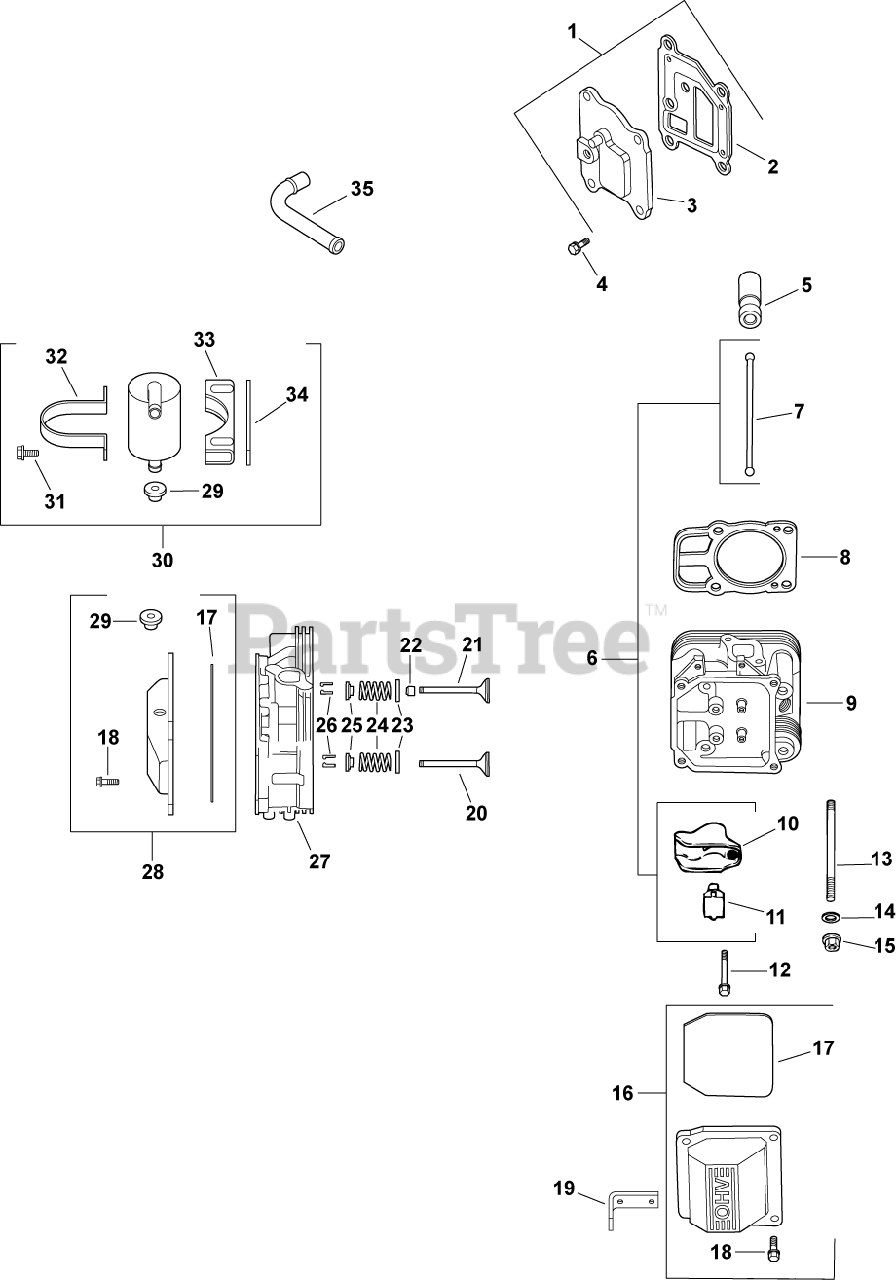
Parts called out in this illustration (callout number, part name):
1	KIT, BREATHER COVER W/GASKET
2	GASKET, BREATHER-USE 24 041 67-S
3	COVER, BREATHER -USE 24 096 125-S
4	SCREW,FLG THD FRM M6X1.0X20-(#25086396S)
5	LIFTER, HYDRAULIC VALVE-USE 25 351 10-S
6	KIT, VALVE TRAIN
7	ROD, PUSH
8	KIT, GSKT CYL HD (C22-23 674CC)
9	HEAD, ASSEM CYLINDER #2 -USE 24 318 113-
10	ARM, ROCKER
11	PIVOT, CYLINDRICAL ROCKER ARM-USE 24 599
12	SCREW, ROCKER ARM PIVOT-USE M-640034-S
13	STUD, M8X1.25
14	WASHER, FLAT 8.6 MM
15	NUT, FLG M8X1.25
16	KIT, VALVE COVER-PLAIN
17	O-RING (YELLOW), VALVE COVER
18	SCREW, FLG M6X1.0X30
19	STRAP, LIFTING-USE 25 445 03-S
20	VALVE, EXHAUST (STD) - USE 32 016 01-S
21	VALVE, INTAKE (STD)
22	SEAL, VALVE STEM - (#2503214S)
23	RETAINER, SPRING
24	SPRING, VALVE
25	RETAINER, VALVE SPRING - USE 25 173 28-S
26	KIT, RETAINER
27	HEAD, ASSEM CYLINDER #1 -USE 24 318 105-
28	KIT, VALVE COVER
29	GROMMET, RUBBER
30	KIT, BREATHR SEPARATR-(#24755241S)
31	SCREW,FLG THD FRM M5X0.8X16-(#25086398S)
32	STRAP, BREATHER - USE 24 755 241-S
33	BRACKET, BREATHER SEPARATOR
34	SPACER
35	HOSE, BREATHER
2401602-S	VALVE, EXHAUST (.25)
2401702-S	VALVE, INTAKE (.25)
